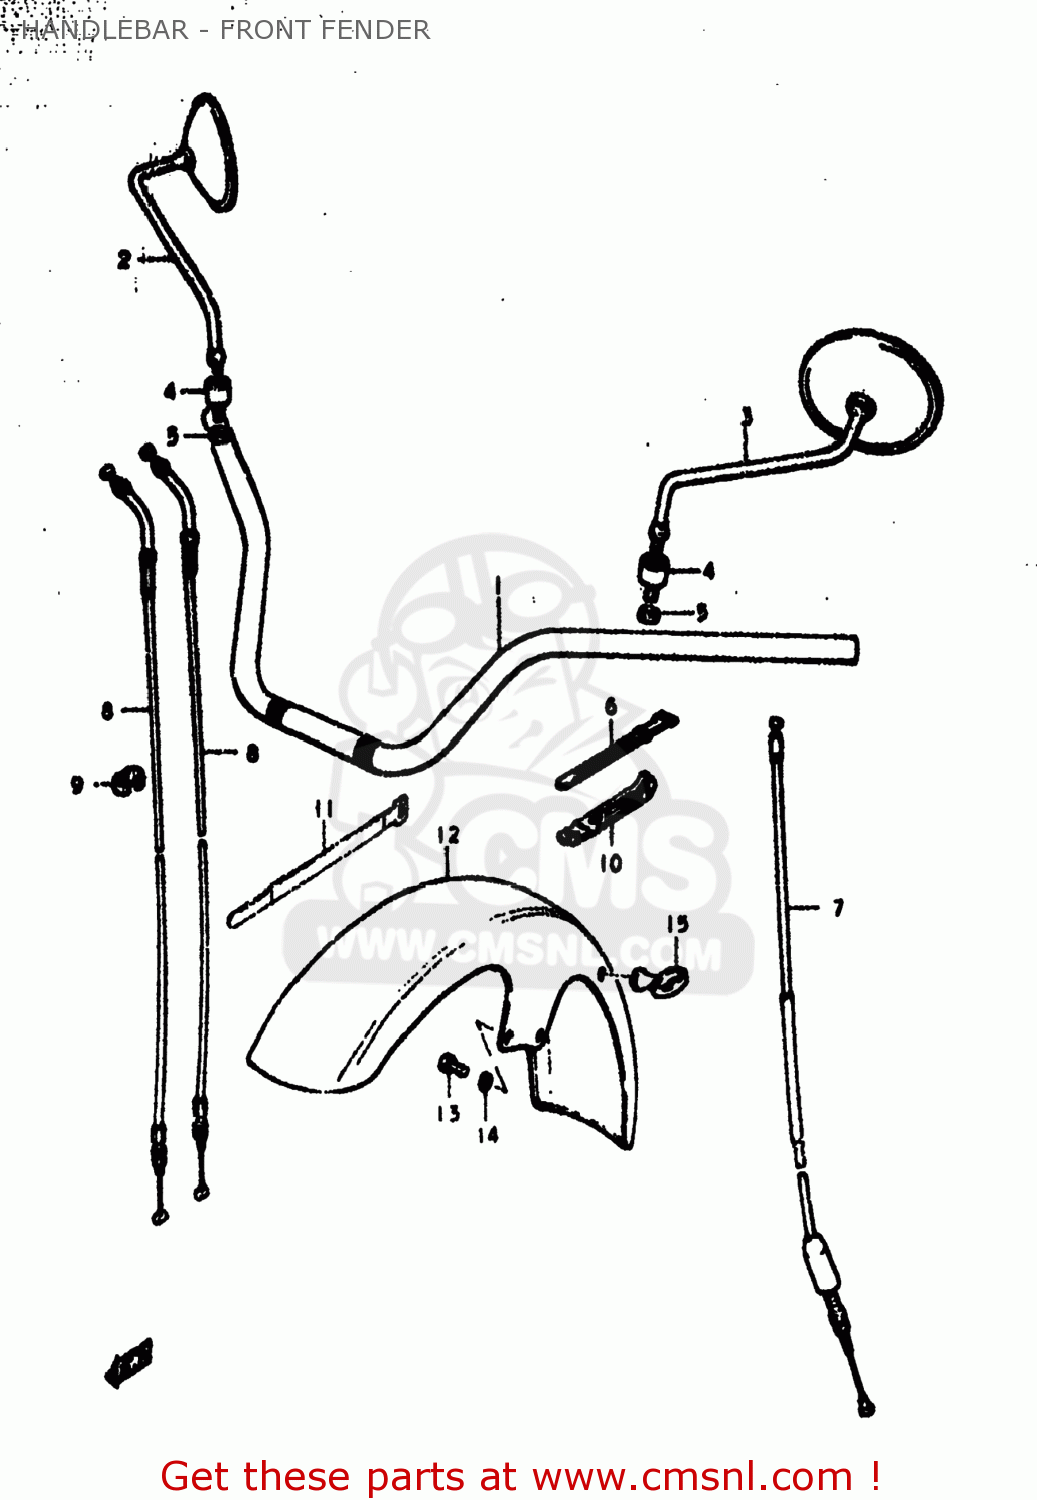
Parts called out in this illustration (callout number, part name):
1	HANDLEBAR
2	MIRROR ASSEMBLY,REAR VIEW
3	MIRROR ASSEMBLY,REAR VIEW
4	CUSHION,REAR VIEW MIRROR
5	NUT
6	CLAMP(L:120)
7	CABLE ASSY,CLUTCH
8	CABLE ASSY,THROTTLE
9	CLIP
10	CLAMP
11	CLAMP
12	FENDER,FR
13	BOLT
14	LOCK WASHER
15	GUIDE,CABLE
